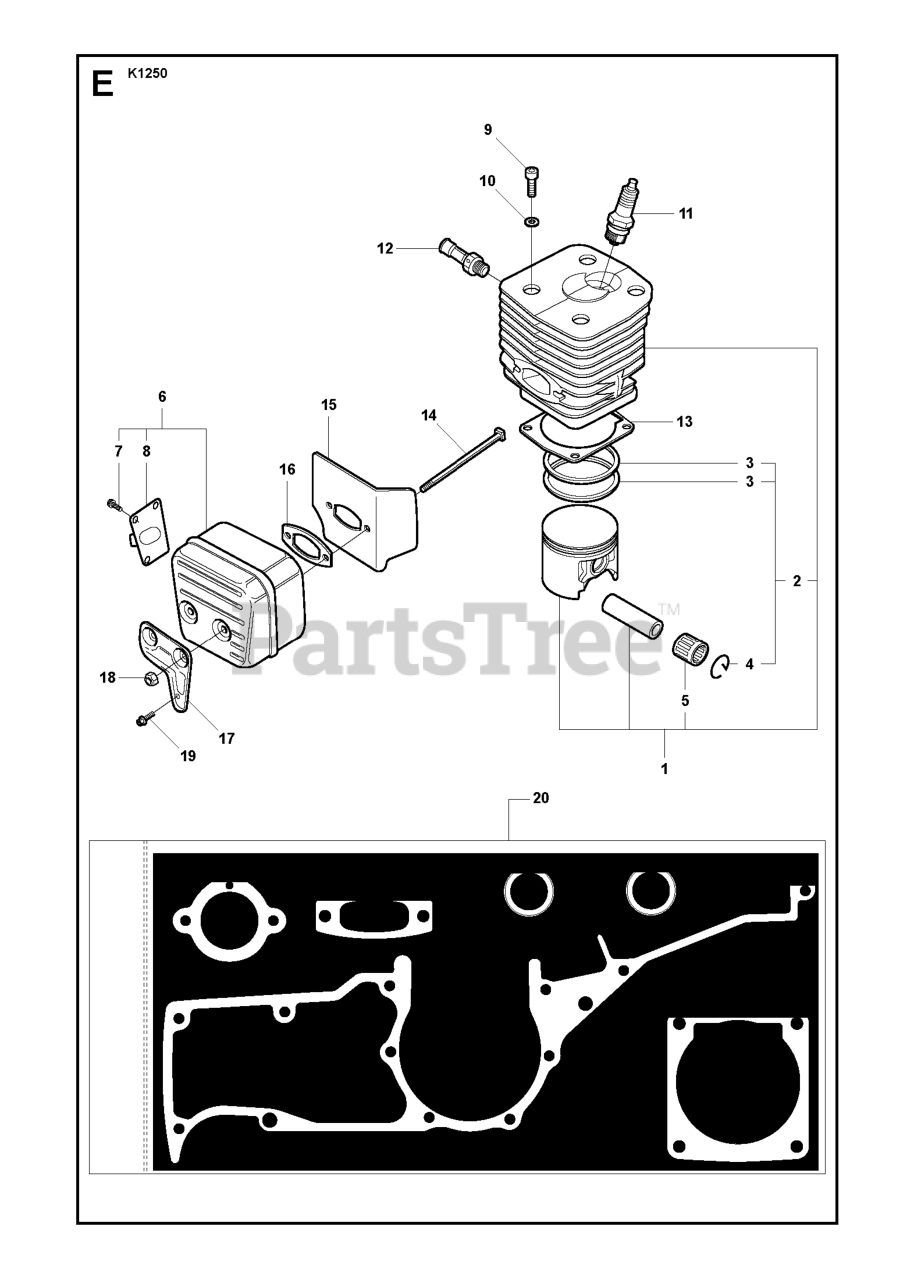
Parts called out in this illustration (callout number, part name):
1	CYLINDER COMP
2	PISTON CPL
3	PISTON RING
5	SUPPORT BUSHING
7	SCREW RXS B8X9.5
8	EXHAUST DUCT
10	WASHER 6.5X11
11	SPARK PLUG RCJ6Y NLA
16	RP GASKET
19	SCREW MC6S 6X16
20	GASKET SET
21	RP GASKET
22	CRANKCASE GASKET
23	SEALING RING
